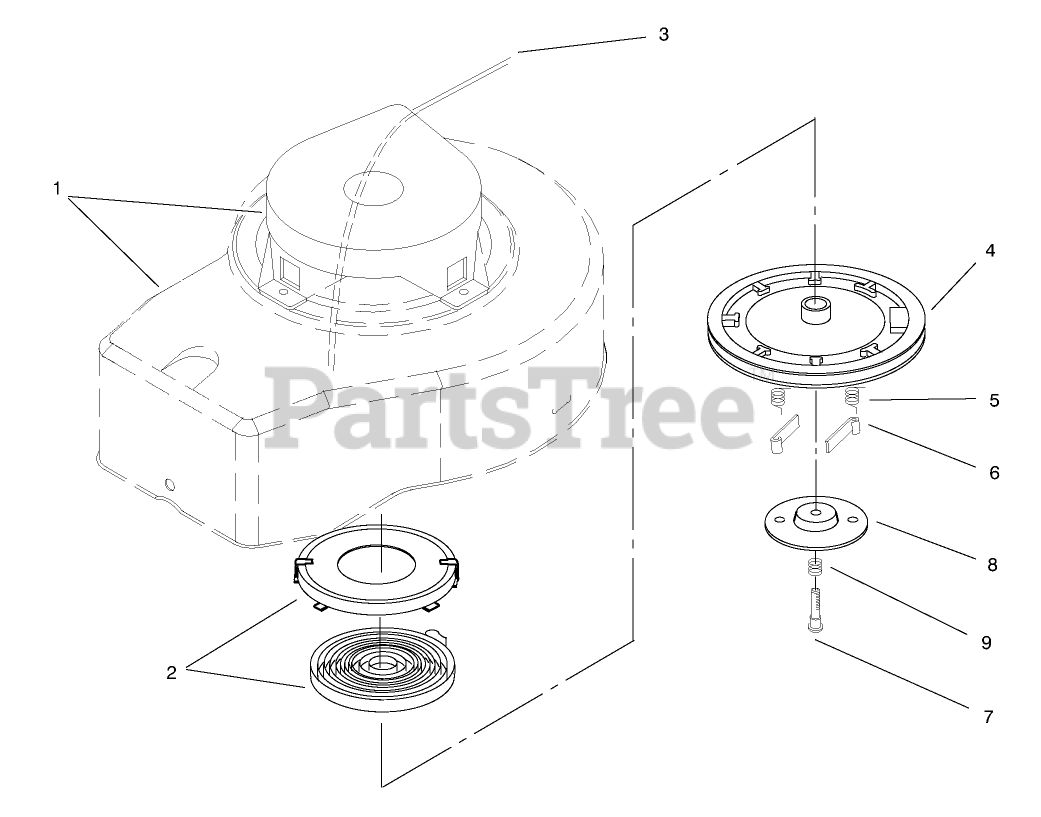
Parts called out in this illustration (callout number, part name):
2	SPRING KEEPER ASM
4	PULLEY ASSEMBLY
5	SPRING- DOG
